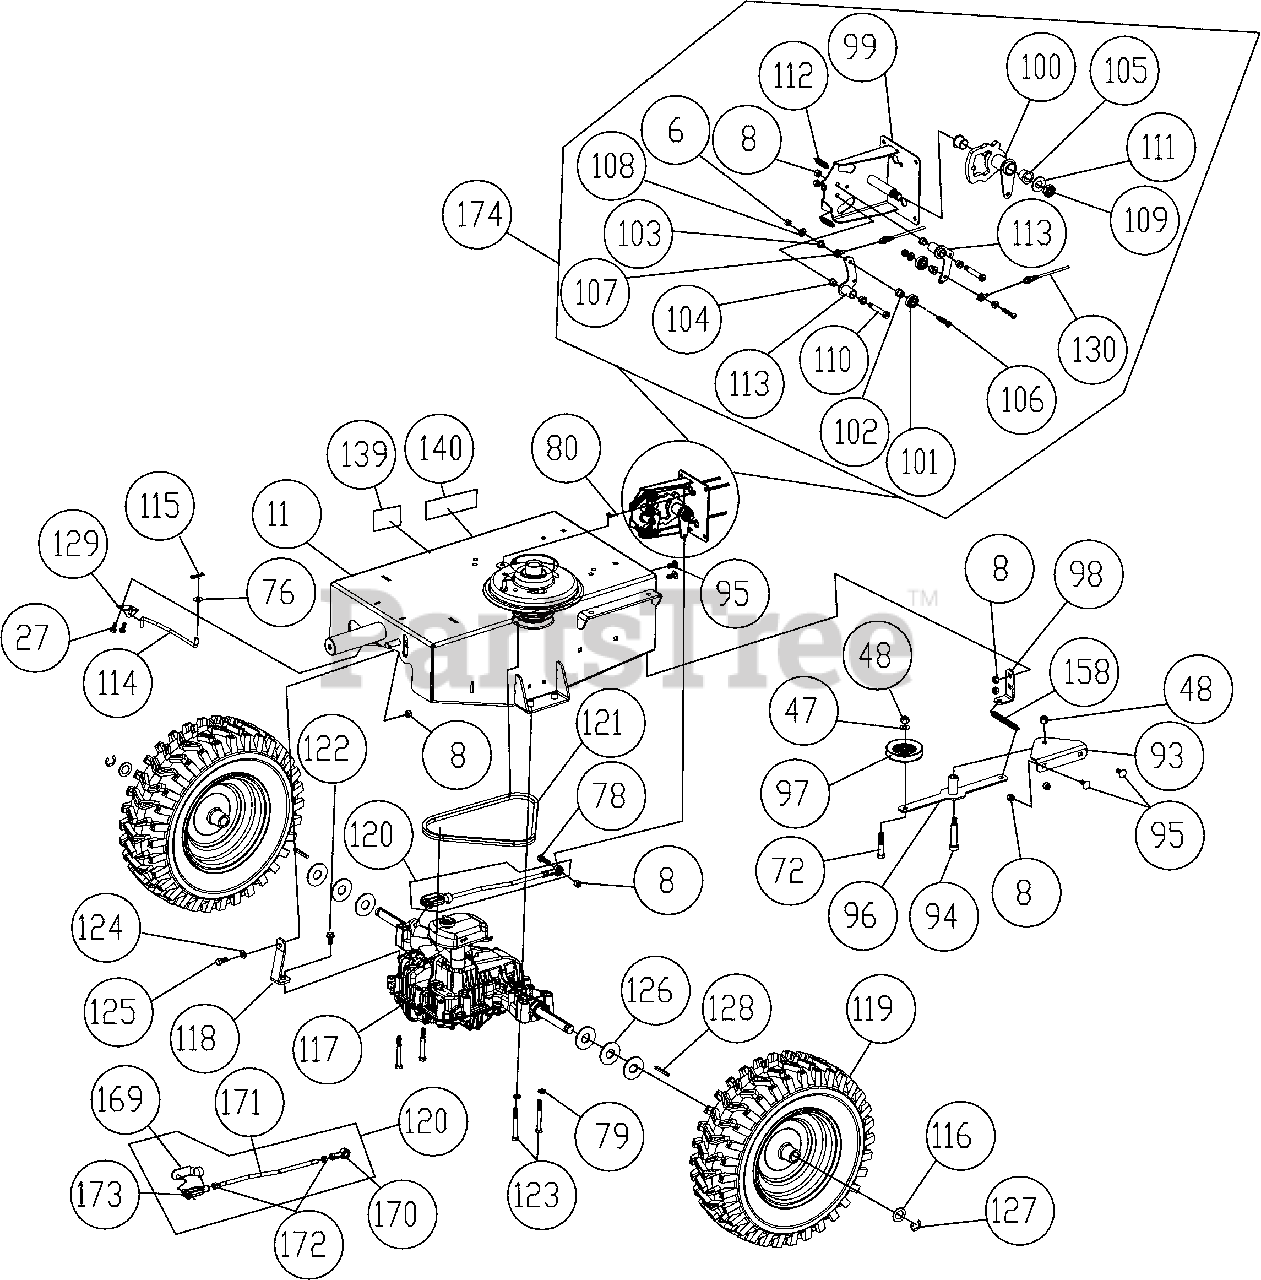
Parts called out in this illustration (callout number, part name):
6	NUT LOCK 1/4”-20 HEX ZP
8	NUT LOCK 5/16”-18
11	ENGINE BASE WA W/LABELS
27	SCREW SELT TAP 1/4-20 X 5/8” HWH TYPE F
47	WASHER 3/8” SAE
48	NUT LOCK 3/8”-16 HEX
72	SCREWCAP 3/8”-16 X 2” HCS ZP
76	WASHER 1/4” SAE
78	SCREWCAP 5/16”-18 X 1” HCS ZP
79	WASHER LOCK 5/16” S/T MED
80	CABLE CLUTCH
93	BRACKET IDLER ARM HYDRO BC26
94	BOLT SHOULDER 1/2” X 2”
95	BOLT CARRIAGE 5/16”-18 X 3/4” PLAIN
96	ARM IDLER DRIVE HYDRO BC26 WA
97	PULLEY INSIDE IDLER BC26
98	BRACKET SPRING IDLER
99	BRACKET SPEED CONTROL BC26
100	PLATE CAM SPEED CONTROL BC26
101	BEARING 1/2” ID X 1.125” OD
102	SPACER STEPPED SPEED CONTROL HYDRO DR
103	SPACER EYELET SPEED CONTROL
104	BUSHING 3/8” ID 1/2” OD X 3/8” LONG
105	BUSHING PIVOT FRAME AE
106	SCREWCAP 1/4-20 X 1 3/4 SKT BUT HD
107	CABLE SPEED CONTROL RT
108	WASHER 1/4” SAE
109	NUT LOCK 5/8”-11 LT WT TH ZP
110	BOLT SHOULDER 3/8” X 1 3/4”
111	WASHER 5/8” FLAT
112	SPRING TENSION
113	BELLCRANK SPEED CONTROL BC26
114	ROD TRANS BYPASS BC26
115	HAIR PIN COTTER 1/4”
116	WASHER .765 ID X 1.25” OD X .06
117	TRANSAXLE TUFF TORQ BC26
118	BRACKET SUPPORT HYDRO TRANSAXLE
119	TIRE 16” AG SP
120	TRANS ROD ASSY
121	BELT HYDRO TRANSAXLE BC26
122	SCREW SELF TAP 5/16” X 3/4” HEX
123	SCREWCAP 5/16”-18 X 2 3/4” HCS ZP
124	WASHER 5/16” SAE
125	SCREWCAP 5/16”-18 X 3/4” HCS ZP
126	WASHER 3/4” SAE
127	RING RETAINING E 3/4”
128	KEY 3/16” SQ X 2 1/8”
129	BRACKET BYPASS ROD
130	CABLE SPEED CONTROL LFT
139	LABEL DRIVE RELEASE
140	LABEL CHOCK WHEELS
158	SPRING IDLER BC
169	SPRING PIN CONTROL ROD
170	SPHERICAL ROD END MSF-5
171	CONTROL ROD
172	NUT JAM 5/16” NC
173	YOKE FEMALE STEEL 5/16” – 24 RH X 2.25”
174	KIT SPEED CONTROL NO CABLES BC26
